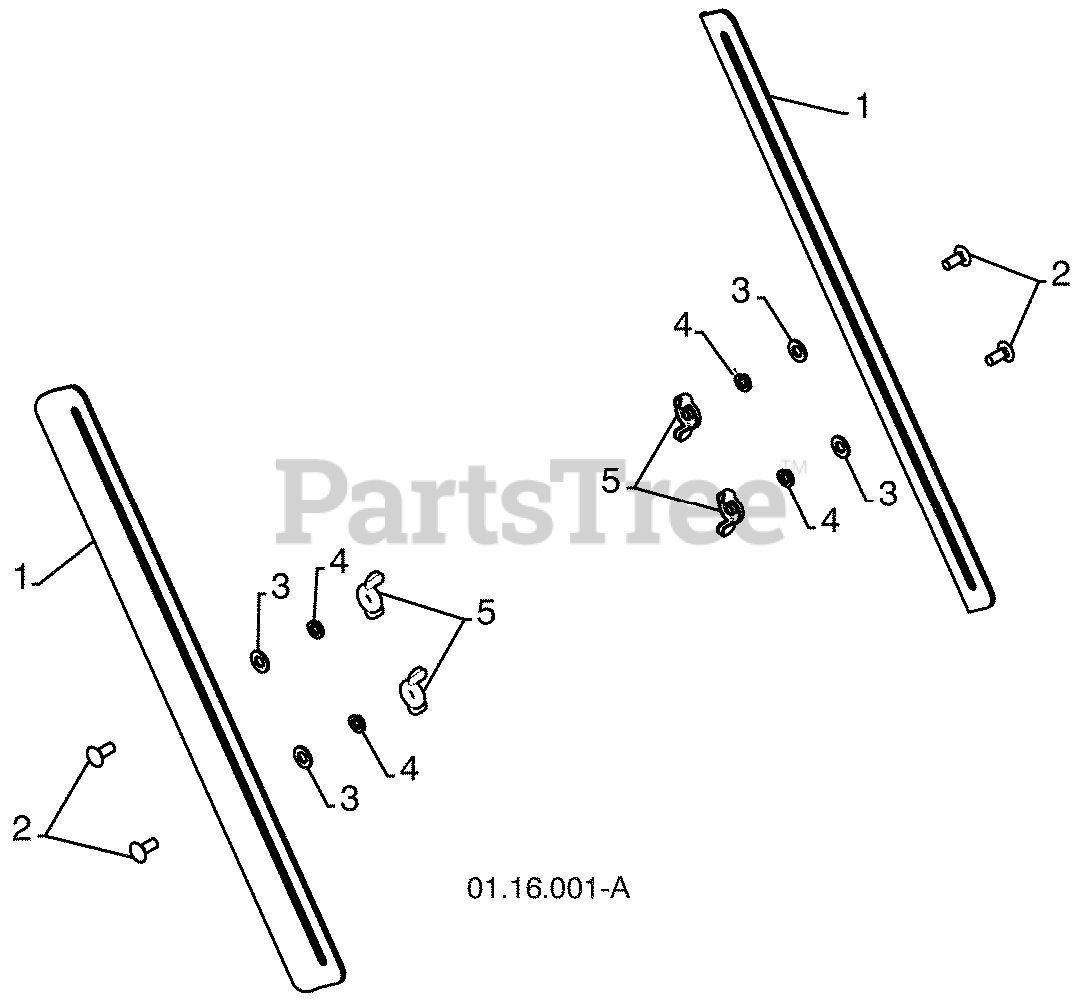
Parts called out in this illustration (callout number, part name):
1	DRIFT CUTTER BAR
2	BOLT
3	WASHER, NYLON FRICTION
4	WASHER.LOCK.HVY.HLCL.SPR.5/16
5	NUT WING PM
